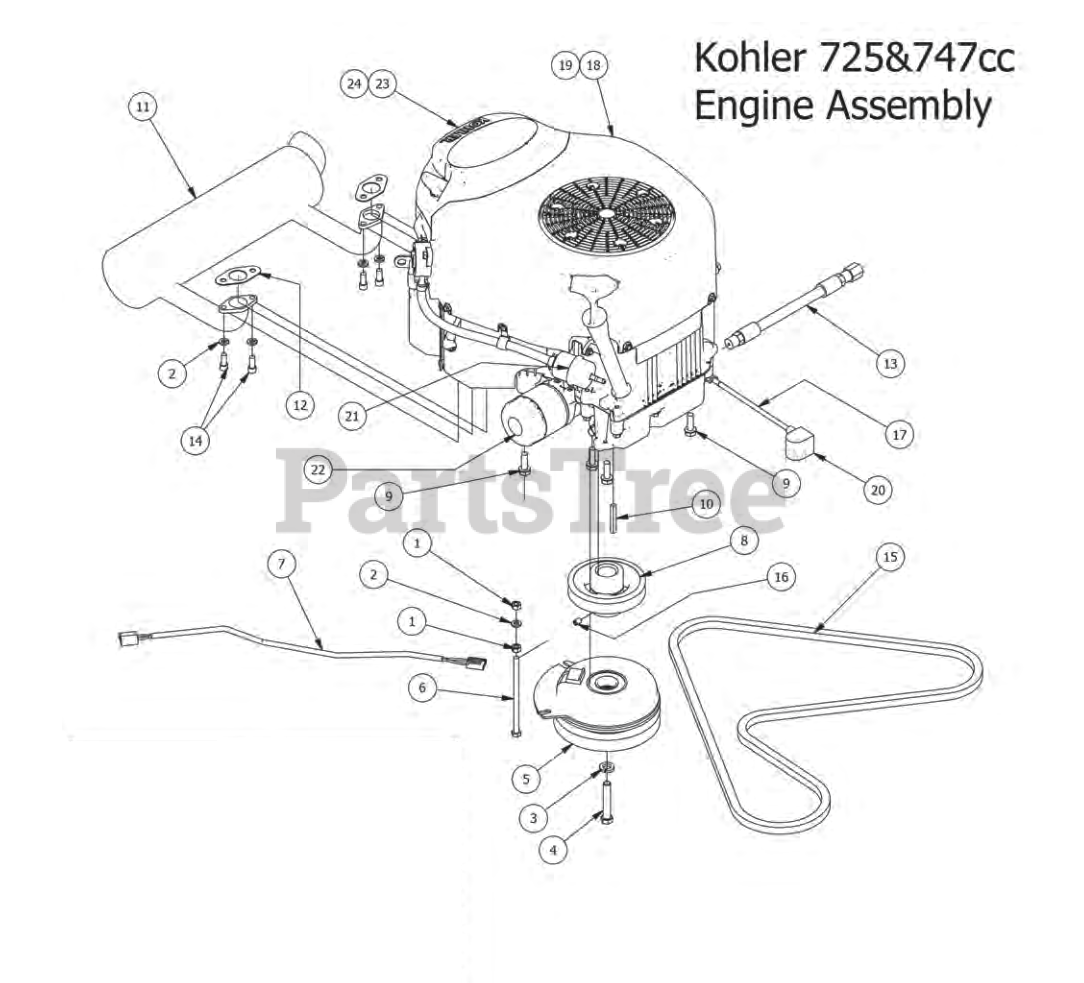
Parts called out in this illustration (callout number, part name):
2	5/16" Lock Washer
3	7/16" Lock Washer
4	7/16" x 2 1/2" Hex Bolt
5	Clutch Assembly
6	5/16-18 x 5-1/2 GR 5 Hex Bolt
7	Clutch Pigtail
8	4 3/4 Motor Pulley
9	3/8 x 1 1/8 bolt.
10	1/4 x 2 Square key Stock
11	Kohler Exhaust
12	Exhaust Gasket
13	Oil drain Hose
14	5/16-18 x 3/4 Socket C/S
16	5/16 Set Screw
17	Starter to chassis cable
18	Kohler-2014 ZT 725cc
19	Kohler-2014 ZT 747cc
20	Black Boot For ground cable
21	725 & 747 Kohler Fuel Filter
22	725 Kohler Oil Filter ZT/MZ
23	725 & 747 Kohler precleaner ZT/MZ
24	725 & 747 Kohler Air Element ZT/MZ
